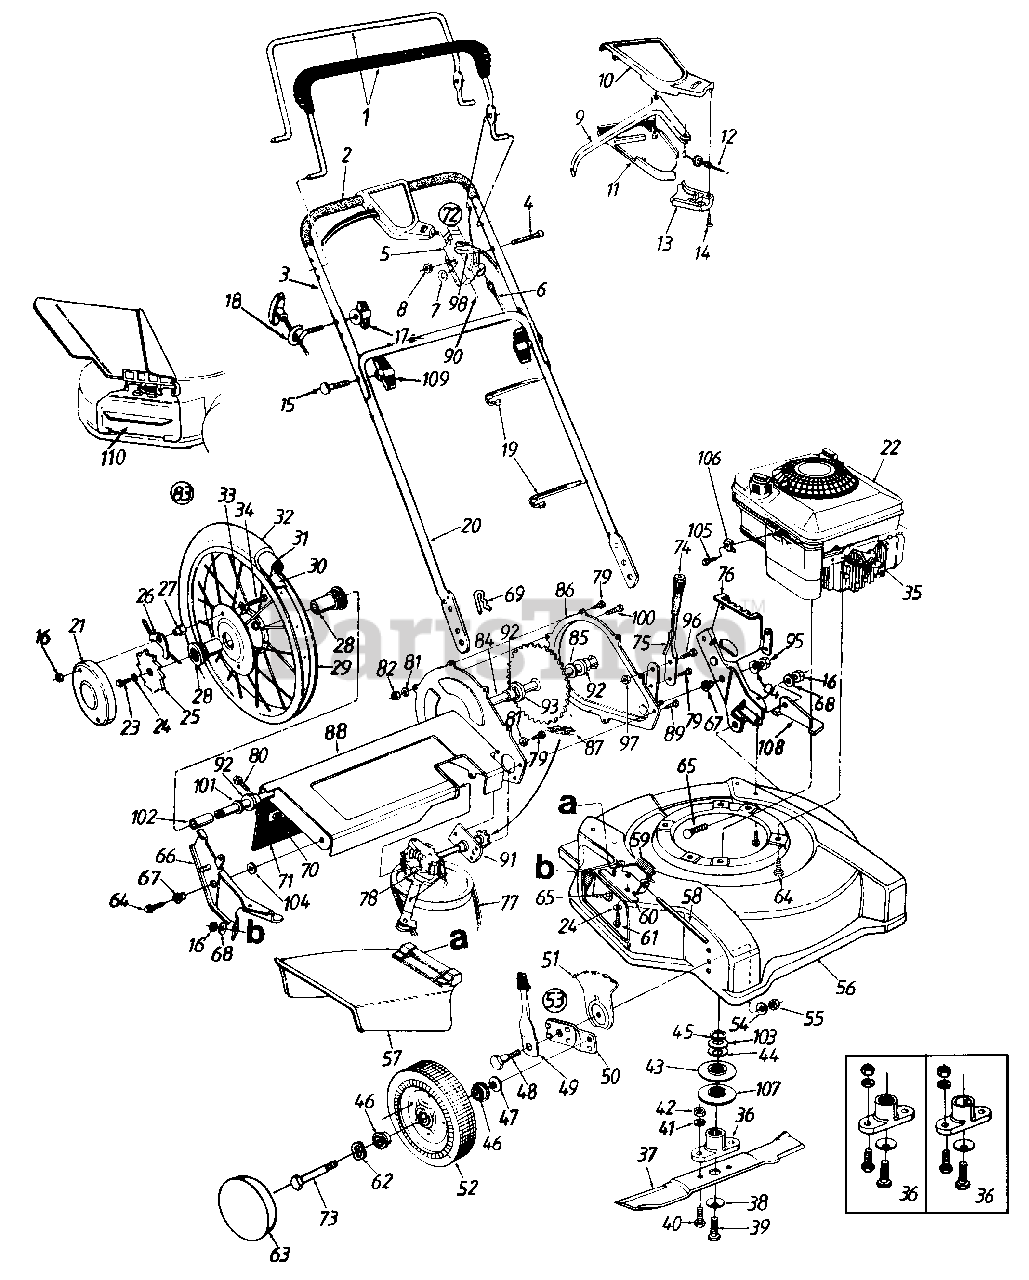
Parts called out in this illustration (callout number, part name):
1	Control Handle Ass'y.
2	Foam Grip
4	Oval C-Sunk Scr.
5	Throttle Body
6	Control Cable - 39" Lg.
7	Spring Wash. .66" I.D.
8	Hex L-Nut 1/4-20 Thd.
9	Control Lever
10	Control Cover Half - Upper
11	Control Cover Half - Lower
12	Self-Propelled Cable - 48" Lg.
13	Cable Mounting Cap
14	Fl-"C" Sunk Hd. Tap Scr. #10 x .75" Lg.
15	Curved Hd. Bolt 5/16-18 x 2" Lg.
16	Hex Nut 5/16-18 Thd.
17	handle Knob 1/4-20 Thd.
18	rope Guide
19	Cable Tie
21	Wheel Cover
22	Engine
23	Hex Bolt 1/4-20 x .75" Lg. (Gr. 5)
24	Bell-Wash. 1/4" I.D.
25	Wheel Ratchet
26	Pawl and Spring Ass'y.
27	Special Hex Nut 5/16-18 Thd.
28	Flange Bearing .63" I.D.
29	Rim Ass'y. Only 16" x 2.1"
30	Rimstrip 16" x 7/8"
31	Inner Tube 16" x 2.12"
32	Chevron Tire 16" x 2.125"
33	Intern. L-Wash. 5/16" I.D.
34	Hex Bolt 5/16-18 x 1.0" (Gr. 5)
35	Spark Plug Boot
36	Blade Adapter Kit
37	22" Blade
38	Bell-Wash. .39" I.D.
39	Hex Bolt 3/8-24 x 1.5" Lg.
40	Hex Bolt 3/8-24 x 1" Lg.
41	L-Wash. 3/8" I.D.
42	Hex Nut 3/8-24 Thd.
43	Upper Pulley Half
44	Fl-Wash. .88" I.D.
45	Crankshaft Spacer
46	ball Bearing 1/2" I.D.
47	Bell-Wash. .38" I.D.
48	Shld. Bolt .5"
49	Spring Lever Ass'y. w/Knob
51	Height Adj. Plate
52	Wheel Ass'y. Comp.
53	Height Adj. Ass'y. Comp. - R.H.
54	Bell-Wash. .39" I.d. x 1.38"
55	Hex Nut 3/8-16 Thd.
58	Hinge Pin
59	Torsion Spring
60	Adapter Plate
61	Hex TT-Tap Scr. 1/4-20 x .5"
62	Wave Wash. .51" I.D. x .78"
63	Hub Cap
64	Hex TT-Tap Scr. 3/8-16 x 1"
65	Carriage Bolt 5/16-18 x .62" Lg.
68	Bell-Wash. 5/16" I.D.
69	Intern. Cotter Pin 5/16" Dia.
70	Retaining Strip
71	Rear Flap
72	Throttle Box Comp.
73	Front Axle Bolt
75	Height Adjustment Lever
78	Transmission Comp. (See Breakdown)
79	Hex Tap Scr. 1/4 x .38" Lg.
80	Hex Tap Scr. 1/4 x .62" Lg.
81	L-Wash. 1/4" I.D.
82	Hex Nut 1/4-20 Thd.
83	Wheel Ass'y. Comp.
84	Sprocket and Axle Ass'y.
85	fl-Wash. .635" I.d. x 1.0" O.D.
90	Throttle Cable
92	Hex Flange Brg. .631" I.D.
93	Spacer .63" I.d. x 1.25"
94	Fl-Wash. .385" I.d. x .87" O.D.
95	Hex L-Nut 3/8-24 Thd.
96	Hex Bolt 3/8-16 x .62" Lg.
97	Flanged L-Nut 3/8-16 Thd.
98	Throttle Lever
100	Hex Bolt 1/4-20 x .5" Lg.
101	Fl-Wash. .632" I.D. x .943"
102	Spacer .628" I.D. x .875"
103	Spr. Wash. .89" I.D.
104	Fl-Wash. .38" I.d. x 1" O.D.
105	Wash. Hd. Scr. #10-32 x .62" Lg.
106	Casing Clamp
107	Lower Pulley Half
108	Deck Bracket
109	Hand Knob
110	Mulching Baffle
